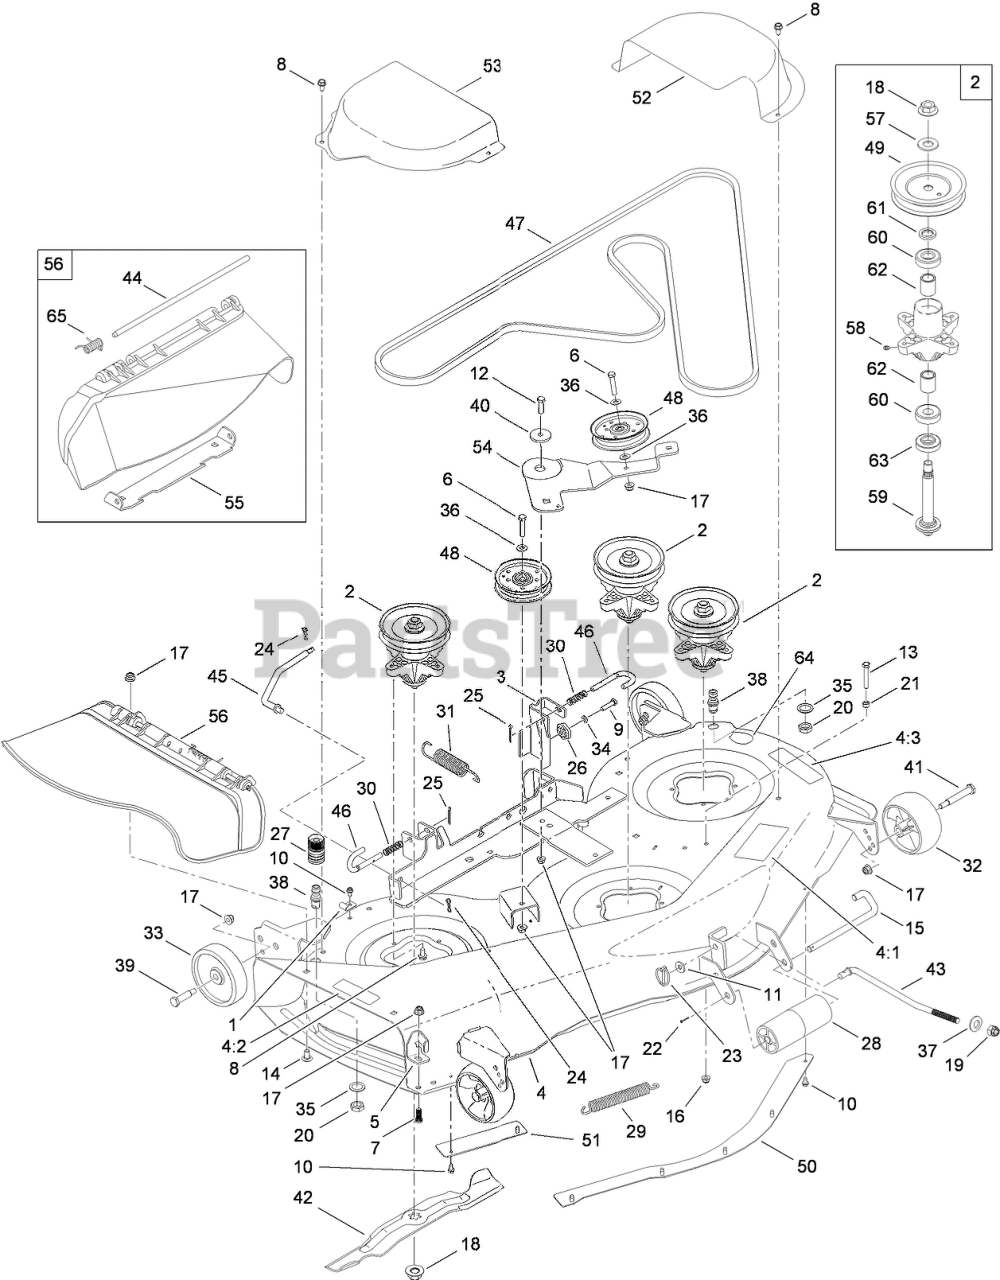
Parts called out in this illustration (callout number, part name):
1	BRACKET-RETAIN, HOOK
2	SPINDLE ASM
3	LH HANGER BRACKET ASM
4	50 INCH DECK ASM
4:1	DECAL-BELT ROUTING, DECK
4:2	DECAL-CHUTE
4:3	DECAL-DECK
5	STOP-CHUTE
6	SCREW-HH
7	SCREW-HH
8	SCREW-TAP
9	SCREW-HH
10	SCREW-HWHTF
11	WASHER-FLAT
12	SCREW-HH
13	SCREW-HH
14	BOLT-CARR
15	PIN-ROLLER
16	NUT-LOCK, FLANGE
17	NUT-LOCK, FLANGE
18	NUT-LOCK, FLANGE
20	NUT-HEX
21	NUT-HEX
22	PIN-COTTER
23	PIN-LYNCH
24	PIN-COTTER
25	PIN-COTTER
26	GEAR-ADJUSTMENT, DECK
27	ADAPTER-NOZZLE, WATER
28	ROLLER-FRONT
29	SPRING-EXTENSION
30	SPRING-COMPRESSION
31	SPRING-LIFT, ASSIST
32	WHEEL-DECK, FRONT
33	WHEEL-DECK, REAR
34	WASHER-LOCK
35	WASHER-LOCK
36	WASHER-FLAT
37	WASHER-BELLVILLE
38	NOZZLE-WATER, DECK
39	BOLT-SHOULDER
40	SPACER-SHOULDER
41	BOLT-SHOULDER
42	BLADE-STAR, 17.90
43	ROD-DECK LIFT, FRONT
44	PIN-HINGE
45	ROD-DECK SWAY
46	PIN-HANDLE, DECK RELEASE
47	BELT-V TYPE
48	PULLEY-IDLER
49	PULLEY
50	SKIRT-CENTER
51	SKIRT-RH
52	COVER-BELT, LH
53	COVER-BELT, RH
54	BRACKET-IDLER
55	BRACKET-CHUTE
56	CHUTE ASM
57	WASHER-FLAT
58	FITTING-GREASE
59	SHAFT-SPINDLE, BLADE (STAR)
60	BEARING-BALL
61	SPACER
62	SPACER
63	SPACER
64	DECAL-DECK WASH SYSTEM
65	SPRING-TORSION
